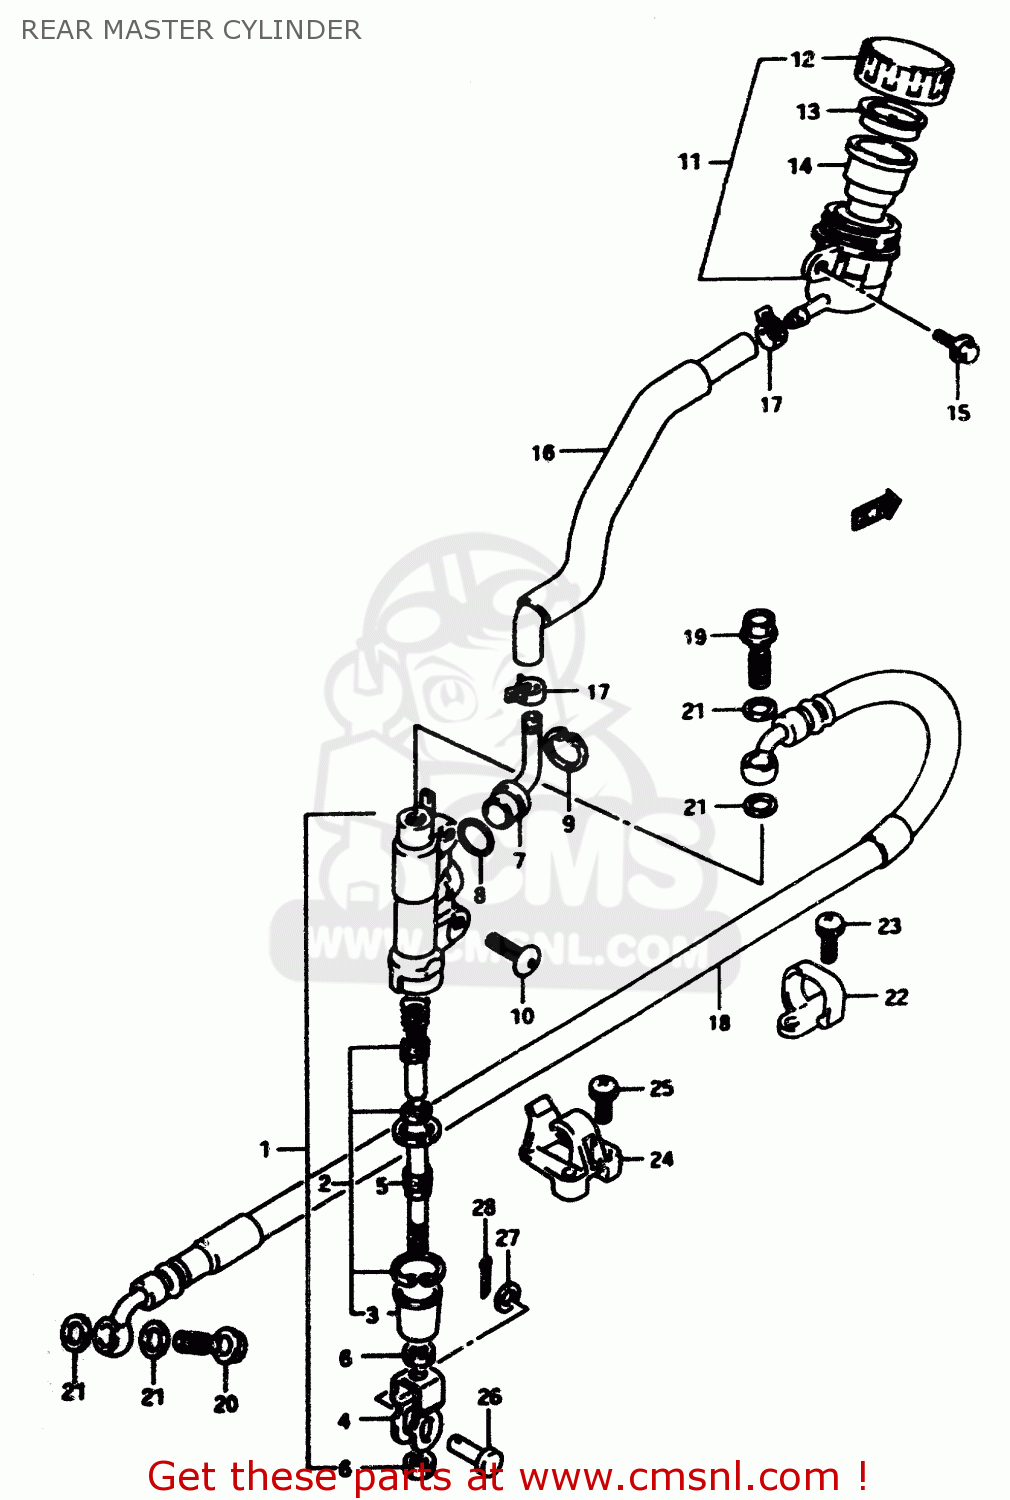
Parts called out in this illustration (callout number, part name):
1	CYLINDER ASSY,RR MASTER
2	PISTON/CUP SET
3	BOOT
4	YOKE
5	ROD,PUSH
6	NUT
7	CONNECTOR
8	O RING
9	CIRCLIP
10	SCREW(6X16)
11	TANK ASSY,RR BRAKE RESERVOIR
12	CAP
13	PLATE
14	DIAPHRAGM
15	BOLT
16	HOSE COMP,RESERVOIR TANK
17	CLIP
18	HOSE,RR BRAKE
19	BOLT UNION
20	BOLT UNION
21	WASHER(10X15X1.5)
22	GUIDE,RR BRAKE HOSE
23	SCREW
24	GUIDE,RR BRAKE HOSE
25	SCREW
26	PIN(8X20)
27	WASHER(8.5X13X1.6)
28	PIN 20X15
